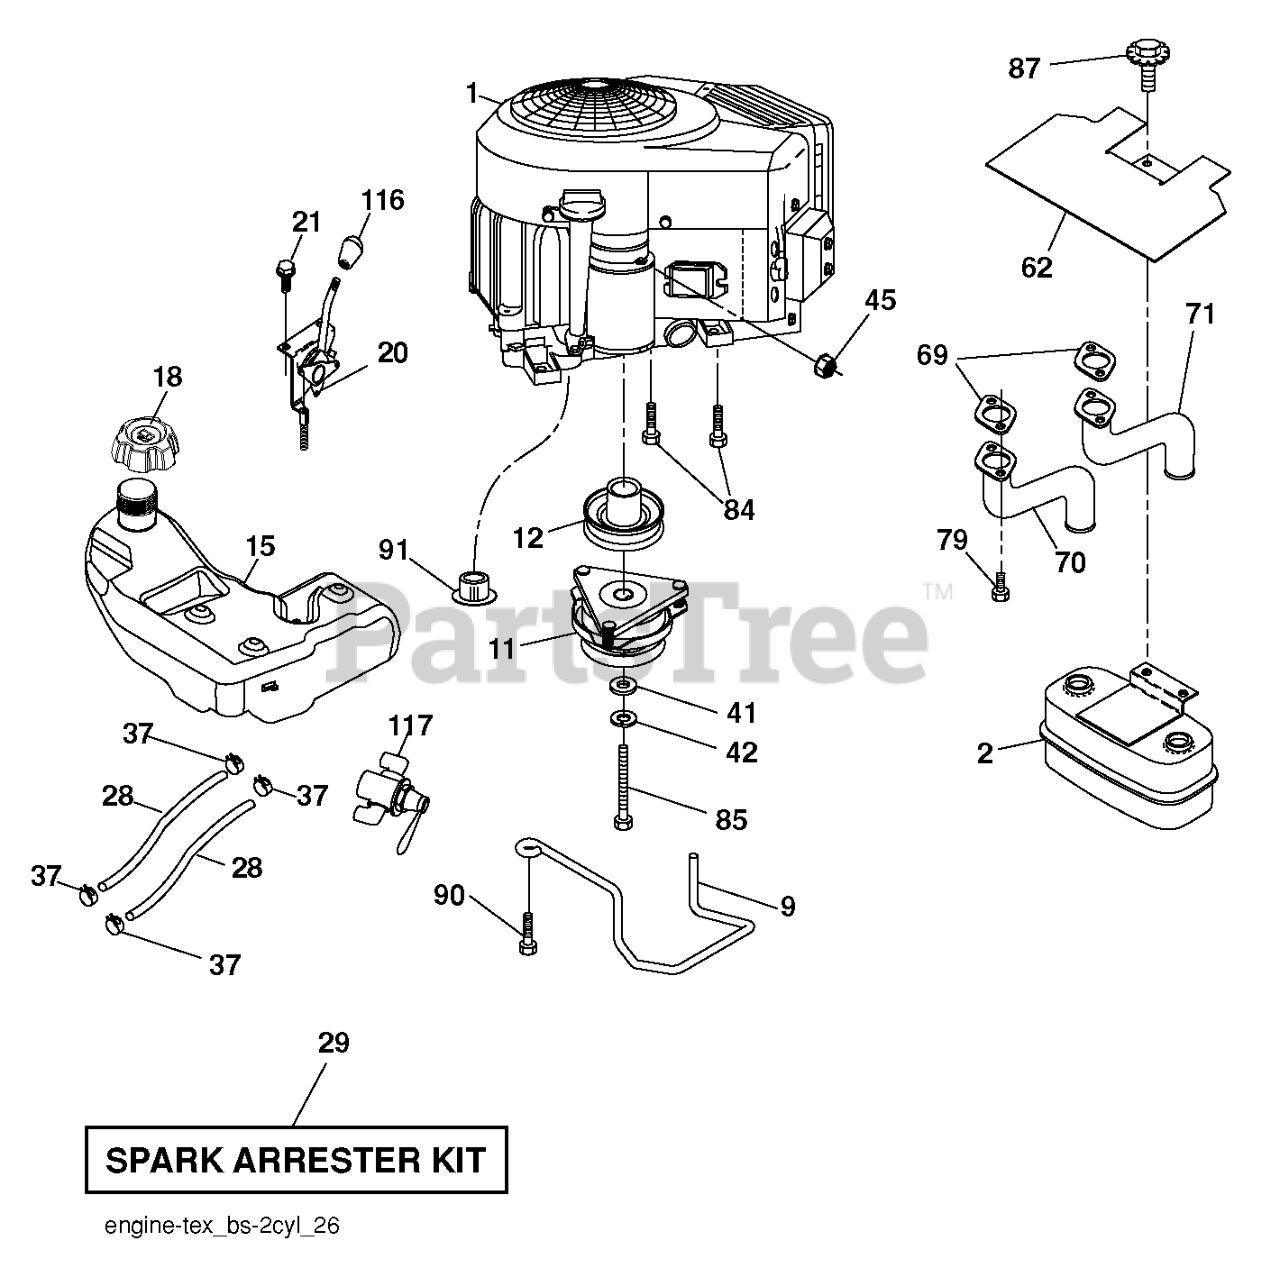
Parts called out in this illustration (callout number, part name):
2	MUFFLER.ASM.TWN.EXTNDED.DFLCTR
9	KEEPER.BELT.ENGINE.4.2
11	CLUTCH.ELECTRIC.LT.48"*
12	PULLEY.ENGINE.TUFFTORQ
18	CAP.FL.R.3'N/CARB.H.CROWN.498
20	CONTROL THROTTLE/CHOKE
21	SCREW.#10 X 0.750.BOS
28	LINE.FUEL.64"REAR.EMIS
29	KIT.SPARK ARRESTOR 794945 B&S
37	HOSE CLAMP
42	LOCKWASHER
45	NUT
62	SHIELD.HEAT.MUFFLER
69	GASKET.MUFFLER
70	RP.EXHAUST.TUBE.LH.BS/TWIN
71	EXHAUST.TUBE.RH.BS/TWIN
79	SCREW.SOCKET.HEAD.5/16-18
84	SCREW.3/8-16
85	BOLT HEX 7/16-20X4-1/4"
87	BOLT.5/16-18UNCX3/4 W/SEMS.BLK
90	SCREW 3/8-16X1
91	BUSHING.1.375OD
116	KNOB - SHIFT
117	VALVE FUEL RESERVE
